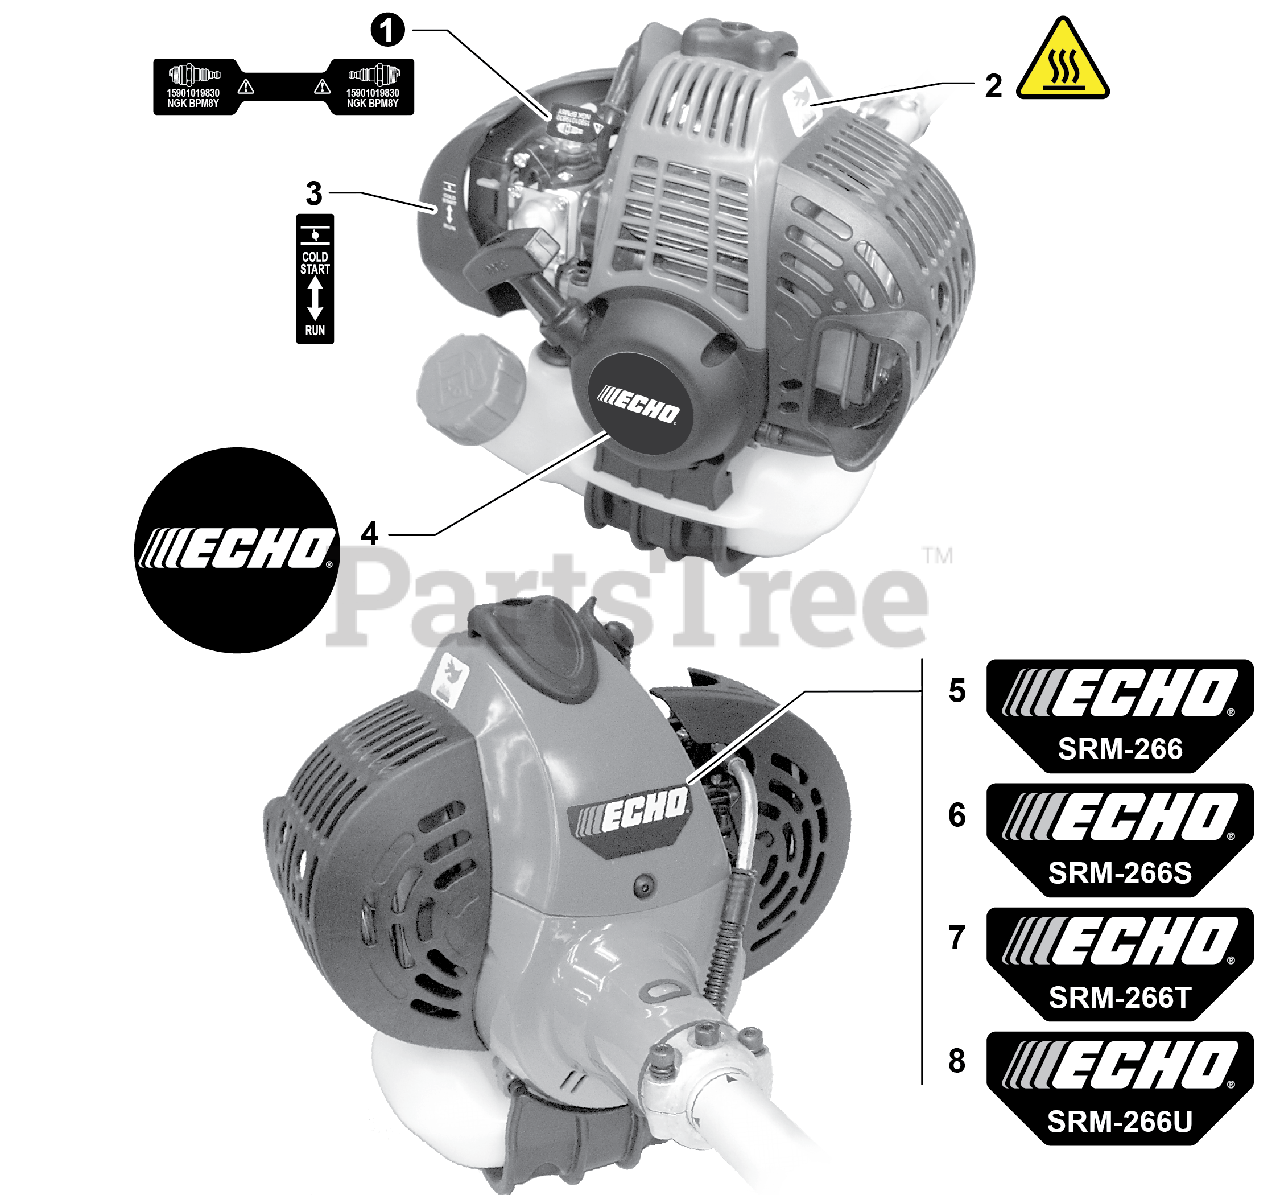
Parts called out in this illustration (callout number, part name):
1	LABEL, SPARK PLUG - BPM8Y
2	LABEL, CAUTION - HOT
3	LABEL, CHOKE
4	LABEL, ECHO
5	LABEL - MODEL SRM-266
6	LABEL - MODEL SRM-266S
7	LABEL - MODEL SRM-266T
8	LABEL - MODEL SRM-266U
